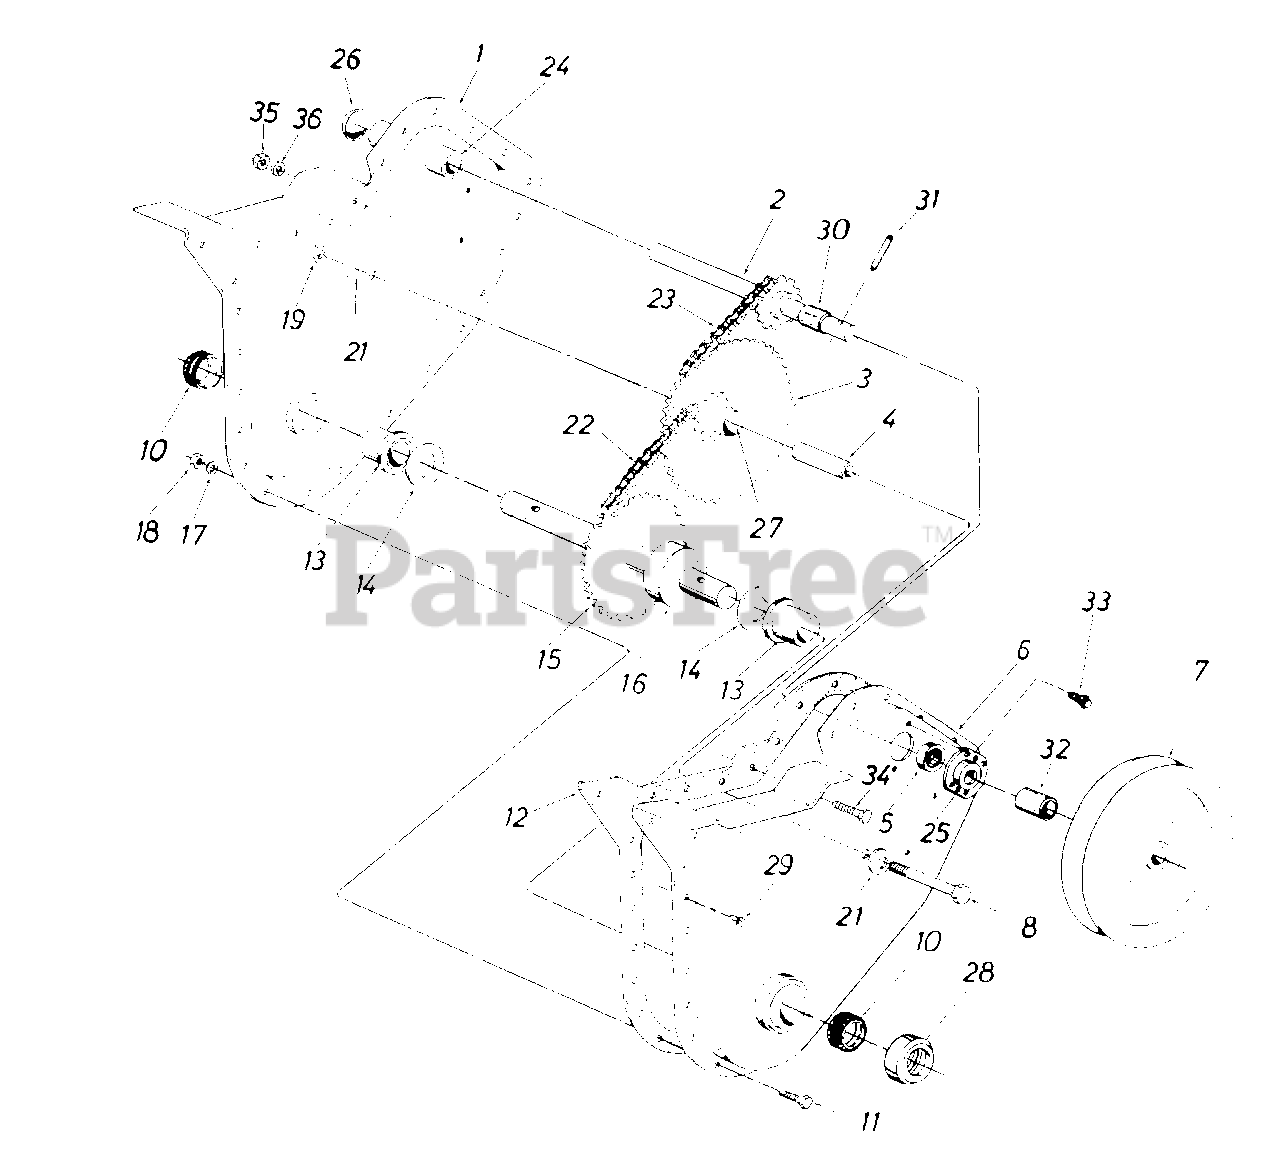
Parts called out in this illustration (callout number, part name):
1	Chain Case Ass'y.--R.H.
2	Input Shaft Ass'y.
3	Hub and Sprocket Ass'y.
4	Bearing Inner Race
5	Ball Bearing
8	Hex Bolt 3/8-24 x 2.5"
11	Hex Bolt 1/4-28 x .625"
12	Gasket
13	Flange Brg. .879" I.D.
14	Fl-Wash. .88" I.D. x 1.5"
15	Tine Shaft Ass'y.
16	Spacer 7/8" I.D.
17	L-Wash. 1/4" I.D.
18	Hex Nut 1/4-28 Thd.
19	Hex Ins. L-Nut 3/8-24 Thd.
21	Bell-Wash. .406" I.D.
22	Chain #420 1/2" Pitch 38 Links
23	Chain #35 .375" Pitch 50 Links
24	Bearing .62" I.D. x .813"
25	Bearing Housing
26	Expansion Plug 13/16" Dia.
29	Hex Wash. Hd. Self-Tap Scr. 1/4-20 x .50" Lg.
30	Spacer .63" I.D. x .77" O.D. x .38" Lg.
31	Spring Pin Spiral 1/4" Dia. x 1-1/2" Lg
32	Spacer .647 x 1.25
33	Hex Wash. Hd. Self-Tap Scr. 1/4-20 x .38" Lg.
34	Hex Bolt 5/16-18 x .75" Lg.
35	Hex Nut 5/16-18 Thd.
36	L-Wash. 5/16" I.D.
